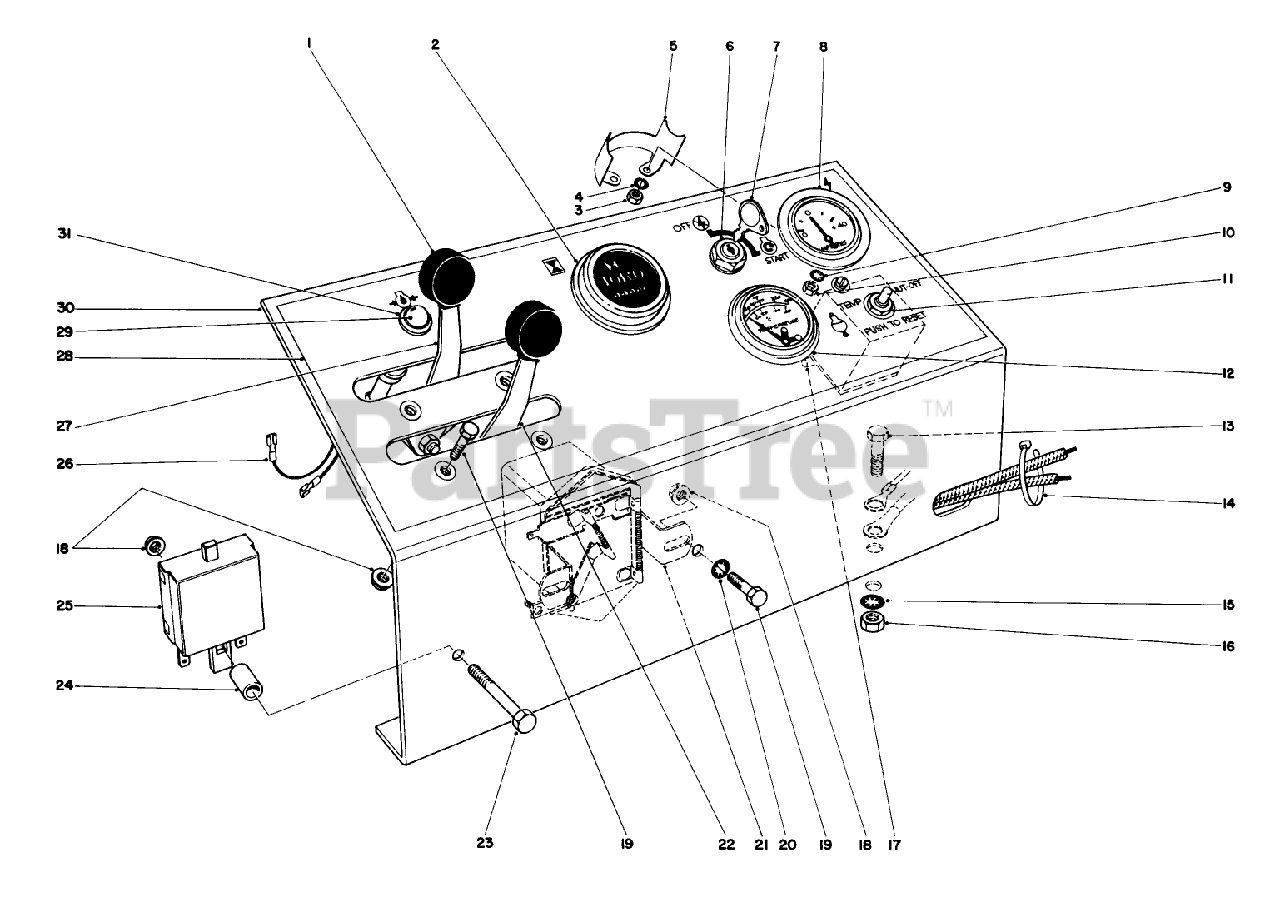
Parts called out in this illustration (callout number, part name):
2	HOUR METER
3	NUT-HEX
4	WASHER-LOCK
5	Clamp
6	SWITCH
7	Key
8	AMMETER GAGE
9	WASHER-LOCK, INTERNAL
10	NUT-HEX
11	TEMP RESET RELAY
12	ENG TEMP SWITCH GAGE
13	SCREW-HH
14	TIE-CABLE
15	WASHER-LOCK, INTERNAL
16	NUT-HEX
17	Fuse Temp Relay 14 AMP SFE
18	NUT-LOCK, FLANGE
20	WASHER-LOCK, INT
21	Regulator
22	Throttle Control (Incl. Ref. #1)
23	SCREW-HH
24	SPACER
25	BUZZER ASM
26	LEAD WIRE ASM
27	Choke Control (Incl. Ref. #1)
28	Decal-Instrument Panel
30	INST PANEL B
31	Warning Light (Incl. Ref. #29)
